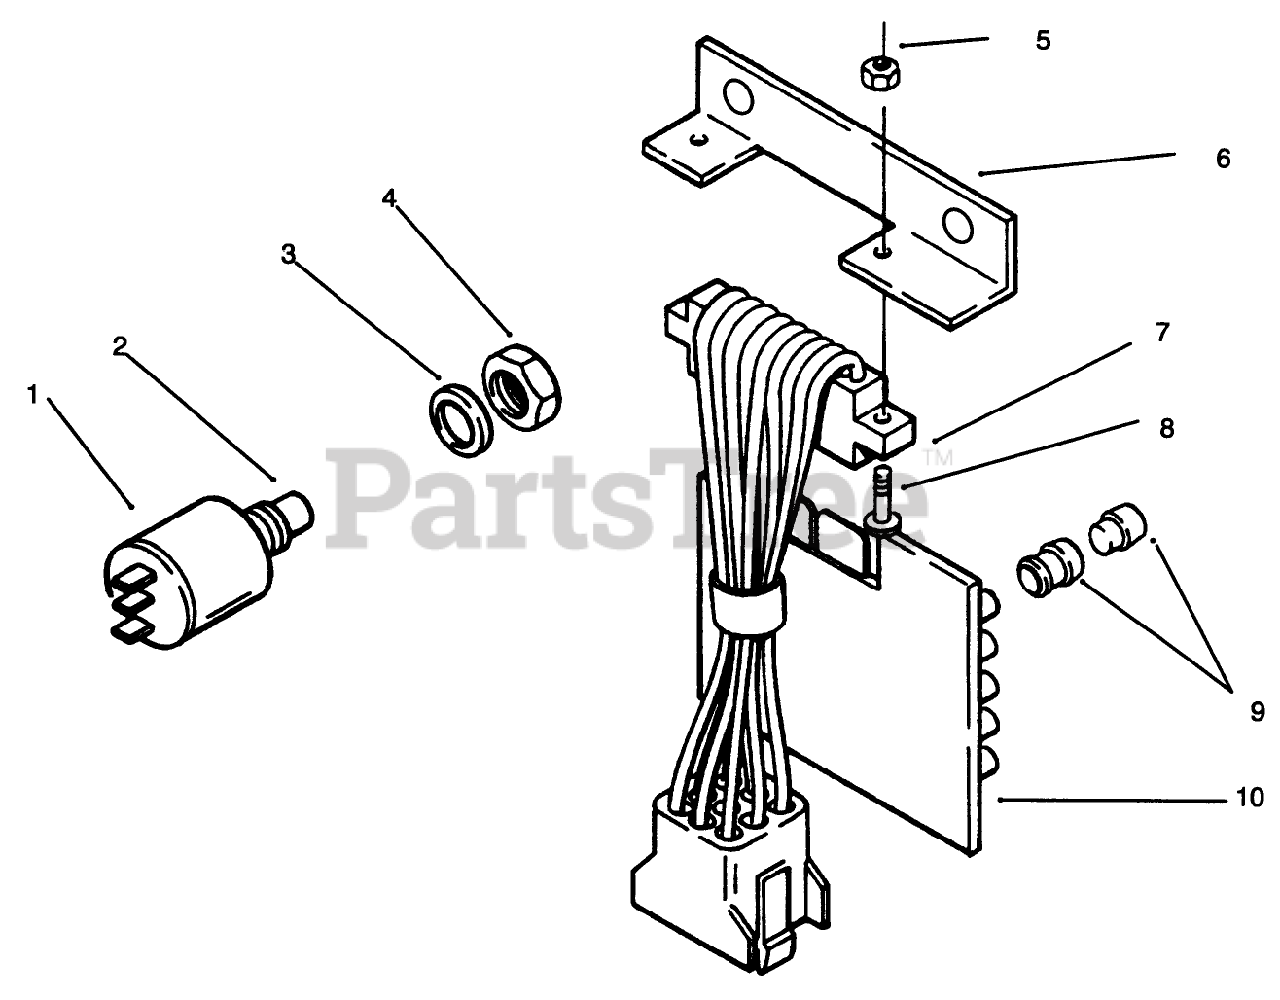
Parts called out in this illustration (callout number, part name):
1	SWITCH-PUSH BUTTON
4	NUT F/W 116796
5	NUT-HEX, NYL INS
6	BRACKET
7	P.C. BOARD HARNESS
8	Screw
9	ASSY LENS & BUSHING
